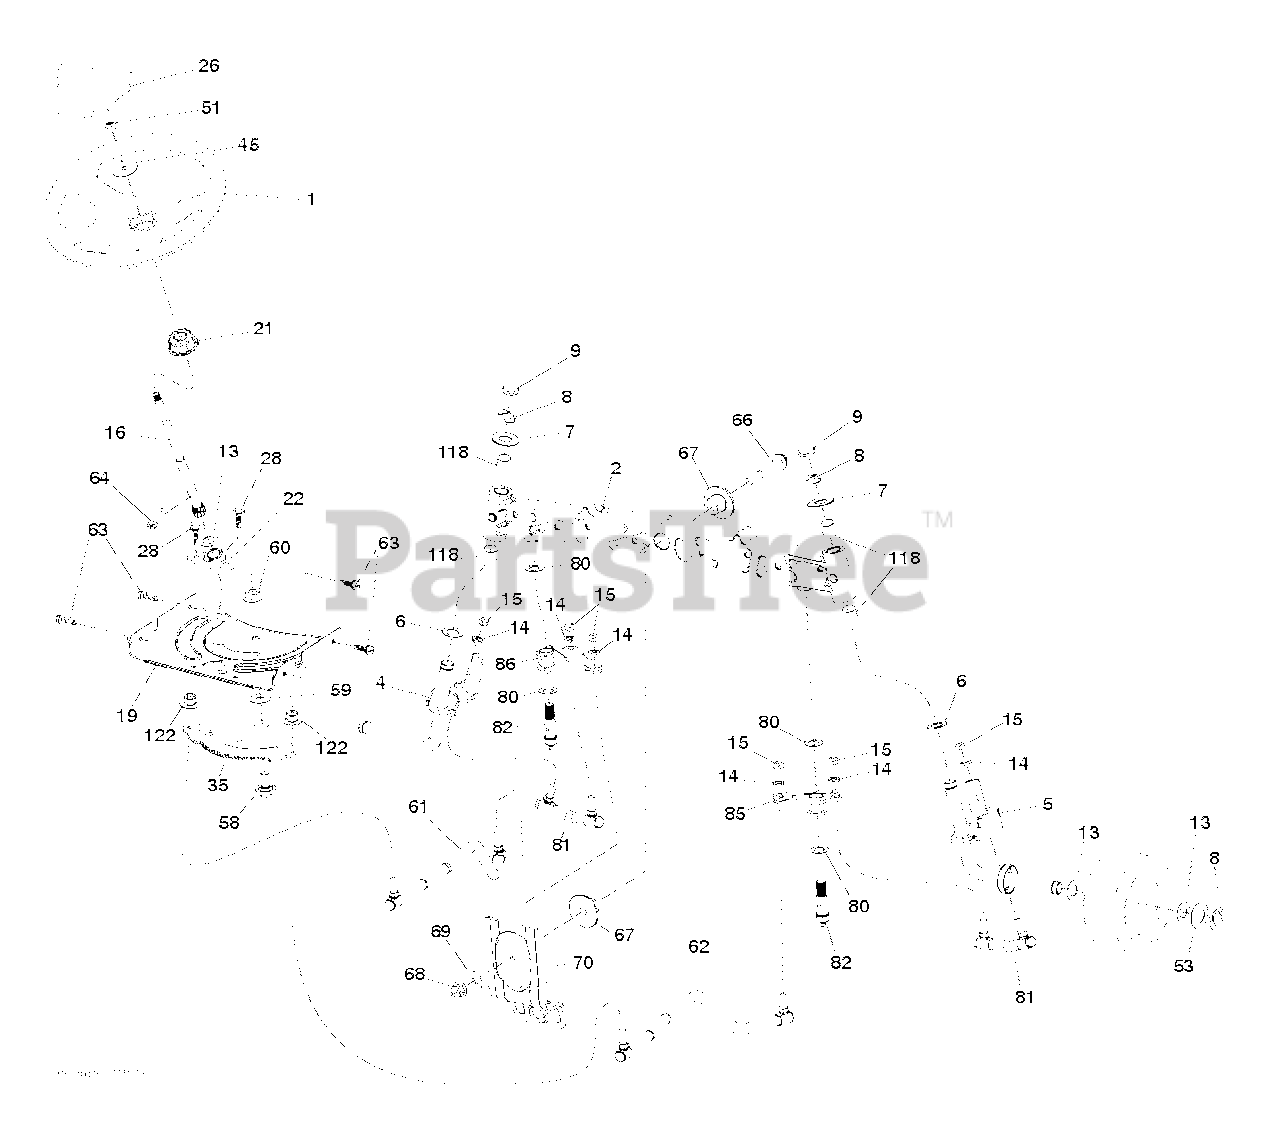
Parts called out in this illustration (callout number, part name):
1	WHEEL.STEER.HUSQ.SR.498.OVMLD
2	RP SUBASM.AXLE.CAST.NZTR.
4	SPINDLE WELDMENT.SPINDLE.LH.15
5	SPINDLE WELDMENT.SPINDLE.RH.15
6	THRUST WASHER
9	CAP.SPINDLE.BLACK
14	WASHER, LOCK 3/8
15	NUT CROWNLOCK 3/8-24
19	PLATE.STEER.DDL.NLT/NG
21	RP STEERING.WHEEL.ADAPTER
22	BUSHING.ASM.STEERING.A
26	INSERT.CAP.WHL.STRG.HUSQ.PREM
28	SCREW, 3/8-16X3/4
35	GEAR GEAR.SECTOR.TEX.NZTR
45	WASHER 9/16"ID, 2 3/8"OD
51	NUT.HEX.1/2-20
53	WASHER.HARDENED
58	BOLT.SHOULDER.SECTOR.P
59	WASHER.THURST.SECTOR.S
60	NUT FLANGE LOCK 5/8-11
61	LINK SUBASM.LINK.DRAG.LH.NZTR
62	TUBE TUBE
63	SCREW
64	RETAINER.CLIP.SPRING.S
66	BOLT HEX FGHD 7/16-14 X 3 SERR
67	BUSHING.PM.FRONT AXLE
68	NUT.LOCK.FLANGE.7/16
69	WASHER.1.5X.505X.118
70	BRKT.DECK.SUSPENSION.F
80	THRUST WASHER
81	LINK SUBASM.LINK.CROSS.NZTR
85	PIVOT SUBASM.PIVOT.RH.NZTR
86	PIVOT SUBASM.PIVOT.LH.NZTR
118	BUSHING, AXLE CAST
122	CAP.GEAR.SECTOR.TEX
